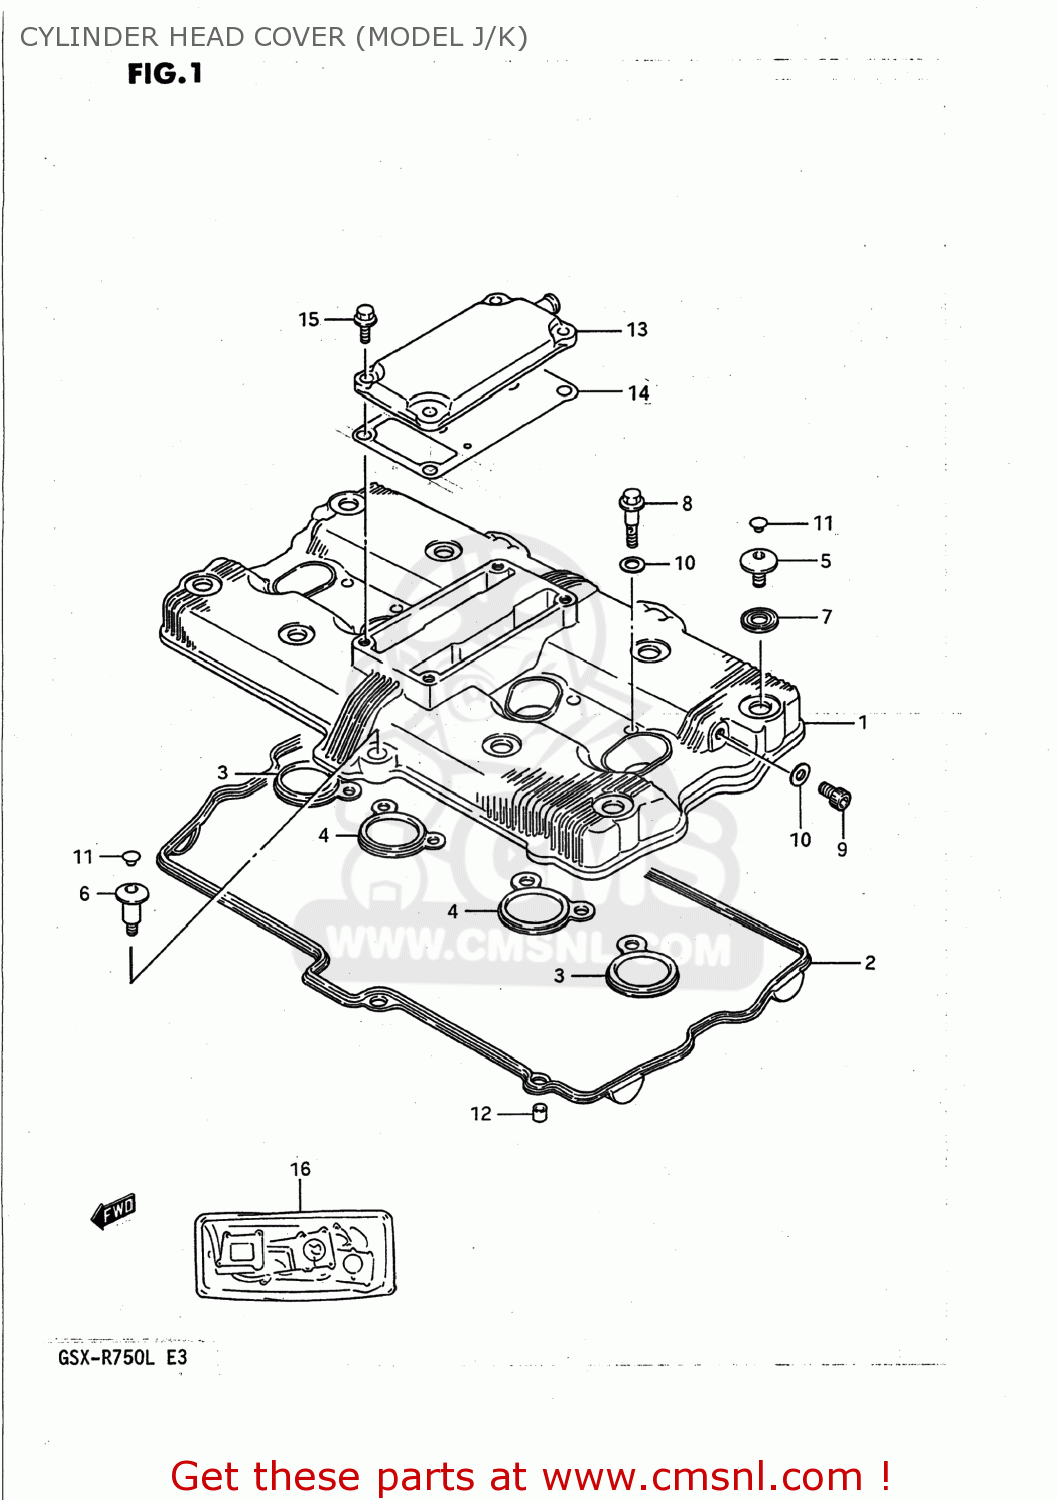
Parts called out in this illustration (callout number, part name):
1	COVER,CYLINDER HEAD
2	GASKET,CYLINDER HEAD COVER (NAS)
3	GASKET,HEAD COVER NO.2 (NAS)
4	GASKET,HEAD COVER NO.3 (NAS)
5	BOLT(7X17.5)
6	BOLT(7X31)
7	WASHER
8	BOLT,UNION 8X35
9	PLUG, HEAD COVER
10	GASKET 8.2X14X1 (NAS)
11	CAP(OD:10)
12	PIN
13	COVER,BREATHER
14	GASKET (NAS)
15	BOLT
16	GASKET
